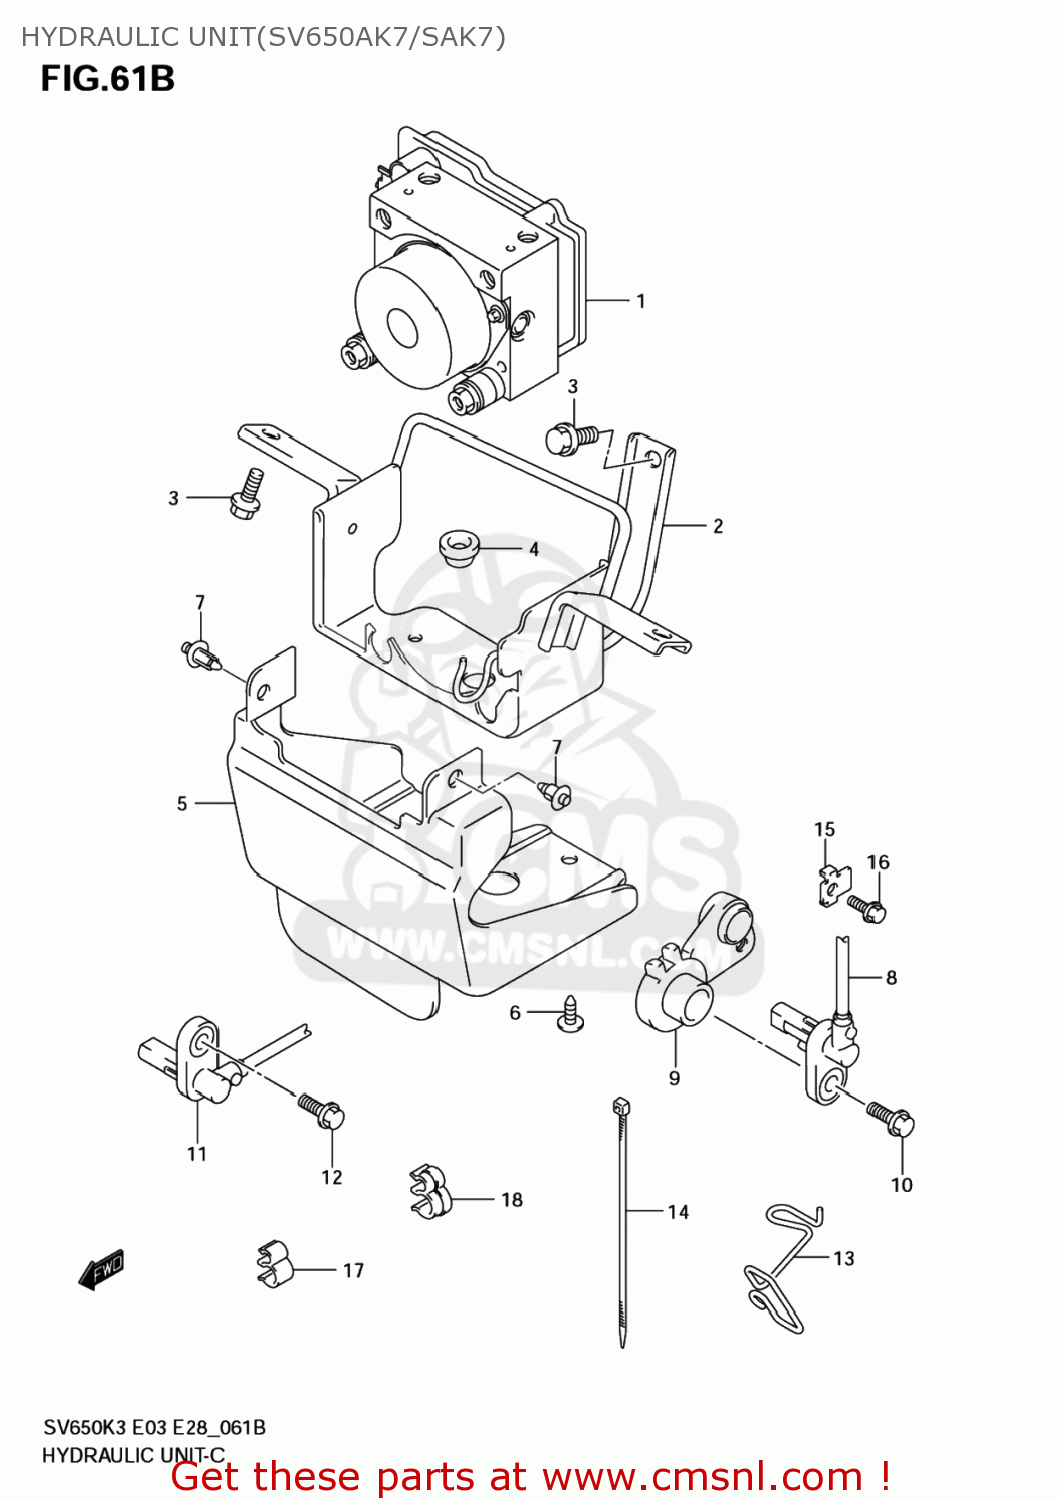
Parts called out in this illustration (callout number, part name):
1	UNIT ASSY,HYDRAULIC ABS
2	HOLDER,HYDRAULIC UNIT ABS
3	BOLT
4	DAMPER,ACTUATOR MOUNT
5	COVER,HYDR ABS UNIT
6	BOLT(6X16)
7	CLIP
8	SENSOR.ABS.V/WL
9	BRACKET,SPEED SENSOR FR
10	BOLT
11	SENSOR,RR WHEEL ABS
12	BOLT
13	GUIDE,SENSOR
14	CLAMP(L:145)
15	GUIDE,SENSOR LEAD
16	BOLT
17	CLAMP
18	CLAMP
